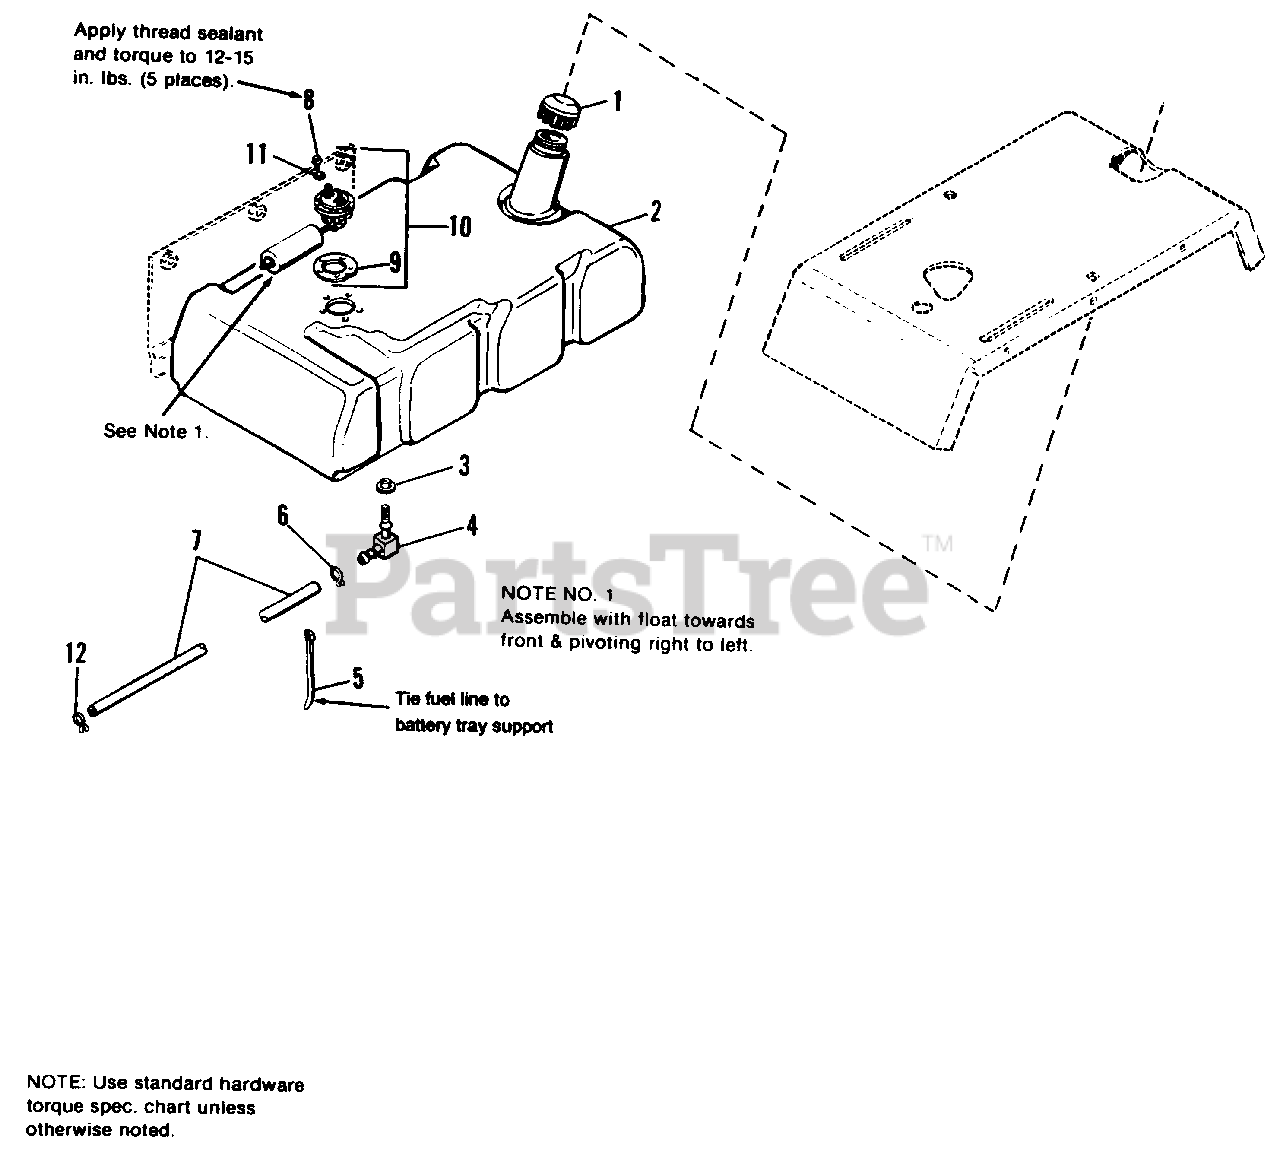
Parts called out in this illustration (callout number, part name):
1	CAP, Gas, Vented
2	FUEL TANK W/FITTINGS & GASKET, W/O Sender (Incl. Ref. Nos. 2,3,4,8,9,11)
2	FUEL TANK W/FITTINGS & INSTALLED SENDER (Incl. Ref. Nos. 2,3,4,8,9,10,11)
4	ELBOW, with Screen
5	TIE, Self-Locking
6	CLAMP, Hose
7	HOSE, Fuel, 38" Long
8	SCREW, Truss Hd., #10-32 x 1/2
9	GASKET, Fuel Sender
10	SENDER, Fuel Level
12	CLAMP, Hose
